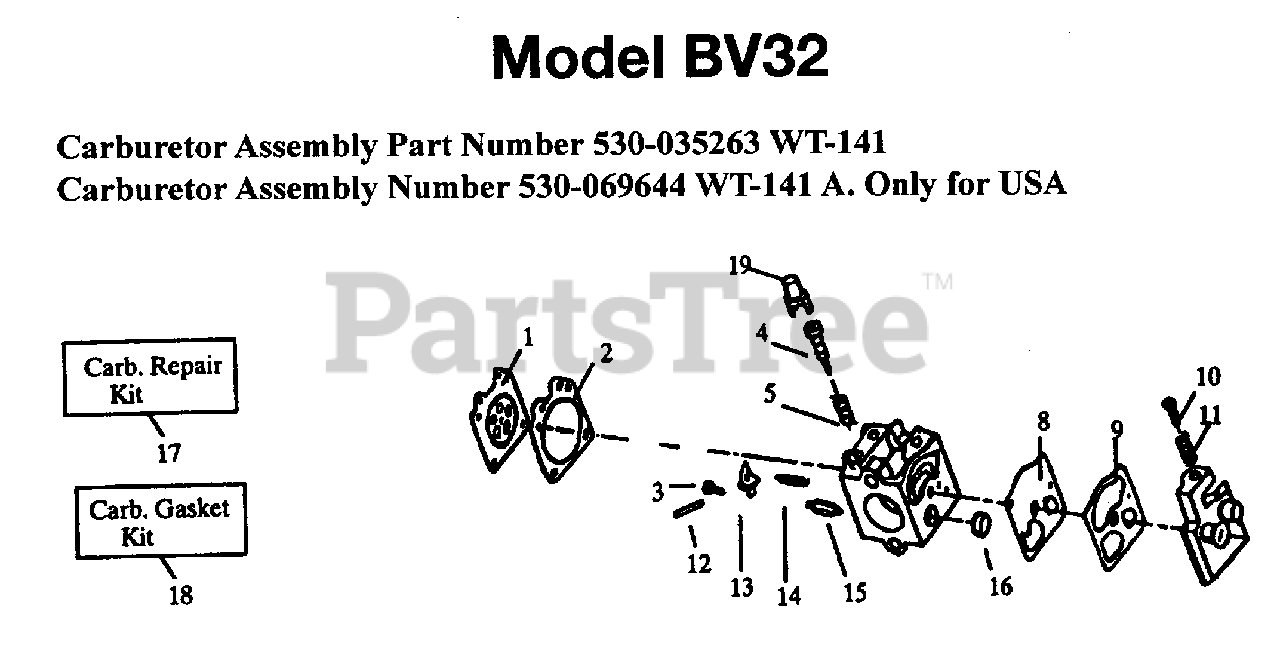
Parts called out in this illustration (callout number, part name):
1	METERING DIAPHRAGM
2	GASKET-METER DIAP
4	MIXTURE NEEDLE (132HBV)
5	SPRING/COMPRESSION
5B	MIXTURE NEEDLE SPRING
8	PUMP DIAPHRAGM
10	SCREW-IDLE SPEED
12	FULCRUM PIN
15	VALVE/INLET.
16	SCREEN-DUTCH TWILL INLE
17	REPAIR PARTS KIT
18	INQUGASKET DIAPHRAGM
19	LIMITER CAP
